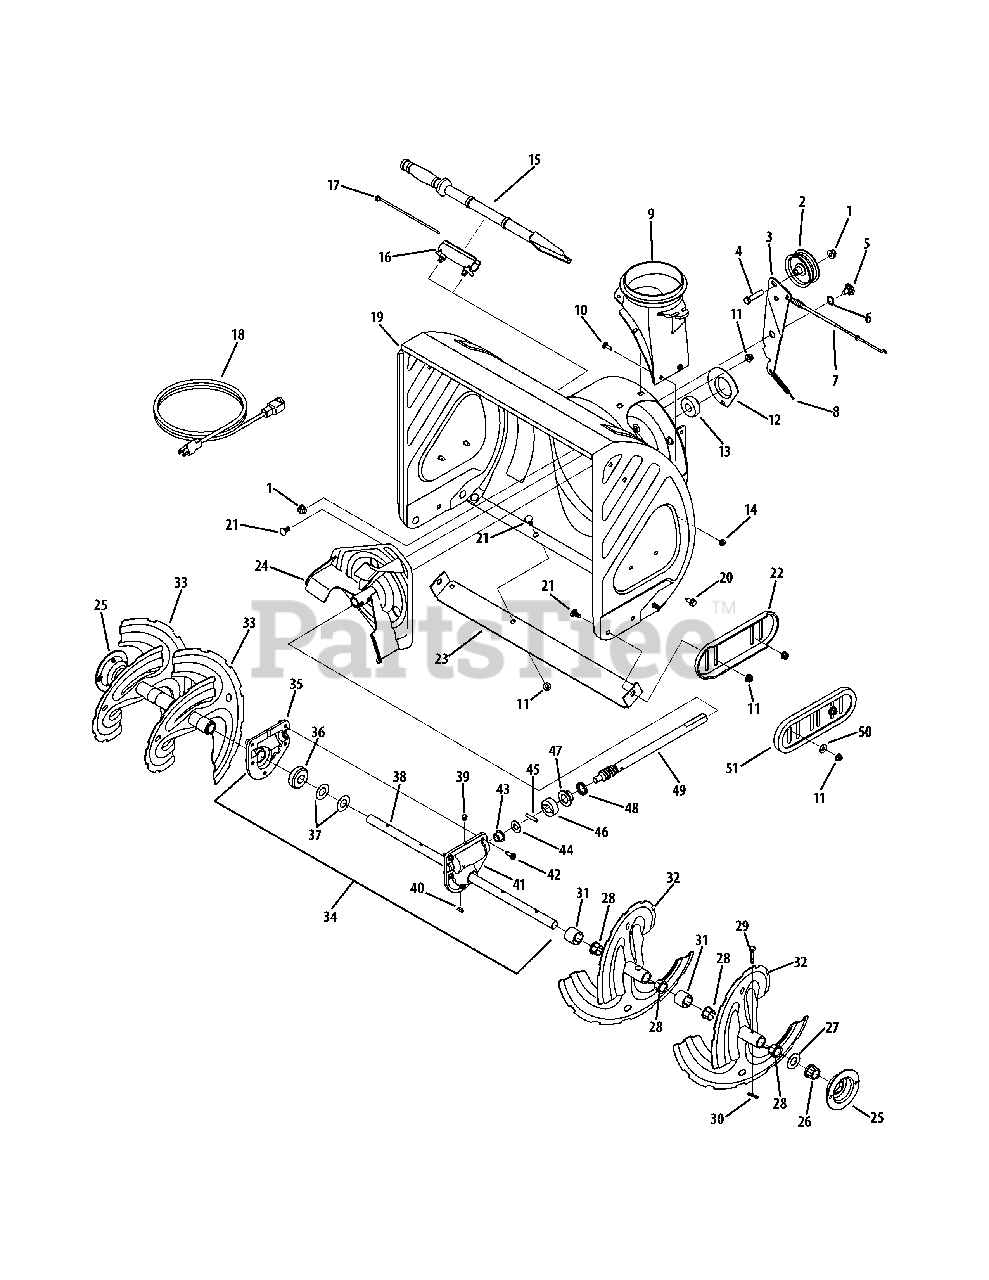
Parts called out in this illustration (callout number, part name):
1	Flange Lock Nut, 3/8-16
2	Idler Pulley
3	Auger Idler Bracket w/ Brake
4	Hex Bolt, 3/8-16 x 1.75
5	Shoulder Screw, .625 x .17 x 3/8-16
6	Wave Washer, .625 x .885 x .015
7	Clutch Cable
8	Extension Spring, .38 OD x 3.6
9	Chute Adapter, 5.0
10	Carriage Screw, 1/4-20 x .75
11	Flange Lock Nut, 5/16-18
12	Bearing Housing
13	Ball Bearing, .75 ID x 1.85 OD
14	Flange Lock Nut, 1/4-20
15	Cleanout Tool
16	Cleanout Tool Mount
17	Cable Tie, 3/16 x .05 x 7.4
18	Extension Cord, 3-Prong
19	Auger Housing, 26"
20	Hex Washer Screw, 5/16-18 x .750
21	Carriage Bolt, 5/16-18 x .750
22	Deluxe Skid Shoe
23	Shave Plate, 2.25 x 26"
24	Impeler Assembly
26	Hex Flange Bearing
27	Flat Washer, .76 x 1.49 x .06
28	Flange Bushing .800 ID x .910 OD
30	Bow-Tie Cotter Pin
31	Spacer, 1.25 OD x .75 ID x 1.00
32	Spiral Assembly, LH
33	Spiral Assembly, RH
34	Gearbox Assembly, 26"
35	Housing Assembly, RH
36	Worm Gear, 2OT
37	Flat Washer, .760 ID x 1.50 OD
38	Auger Axle, 26"
39	Plug, 1/4 x .437
40	Hi-Pro Key, 3/16 x 5/8
41	Housing Assembly, LH
42	Hex Washer Screw, 1/4-20 x .750
43	Flng. Bearing, .50 ID x .75 OD x .59
44	Flat Washer, .51 x 1.12 x .06
45	Dowel Pin, .25 OD x 1.25
46	Thrust Collar, .756 ID x .600
47	Flng. Bearing, .75 ID x 1.0 OD x.59
48	Oil Seal, .75 x 1.131 x .188
49	Worm Shaft, .75 OD
50	Flat Washer, .349 x .879 x .063
51	Deluxe Polymer Skid Shoe
